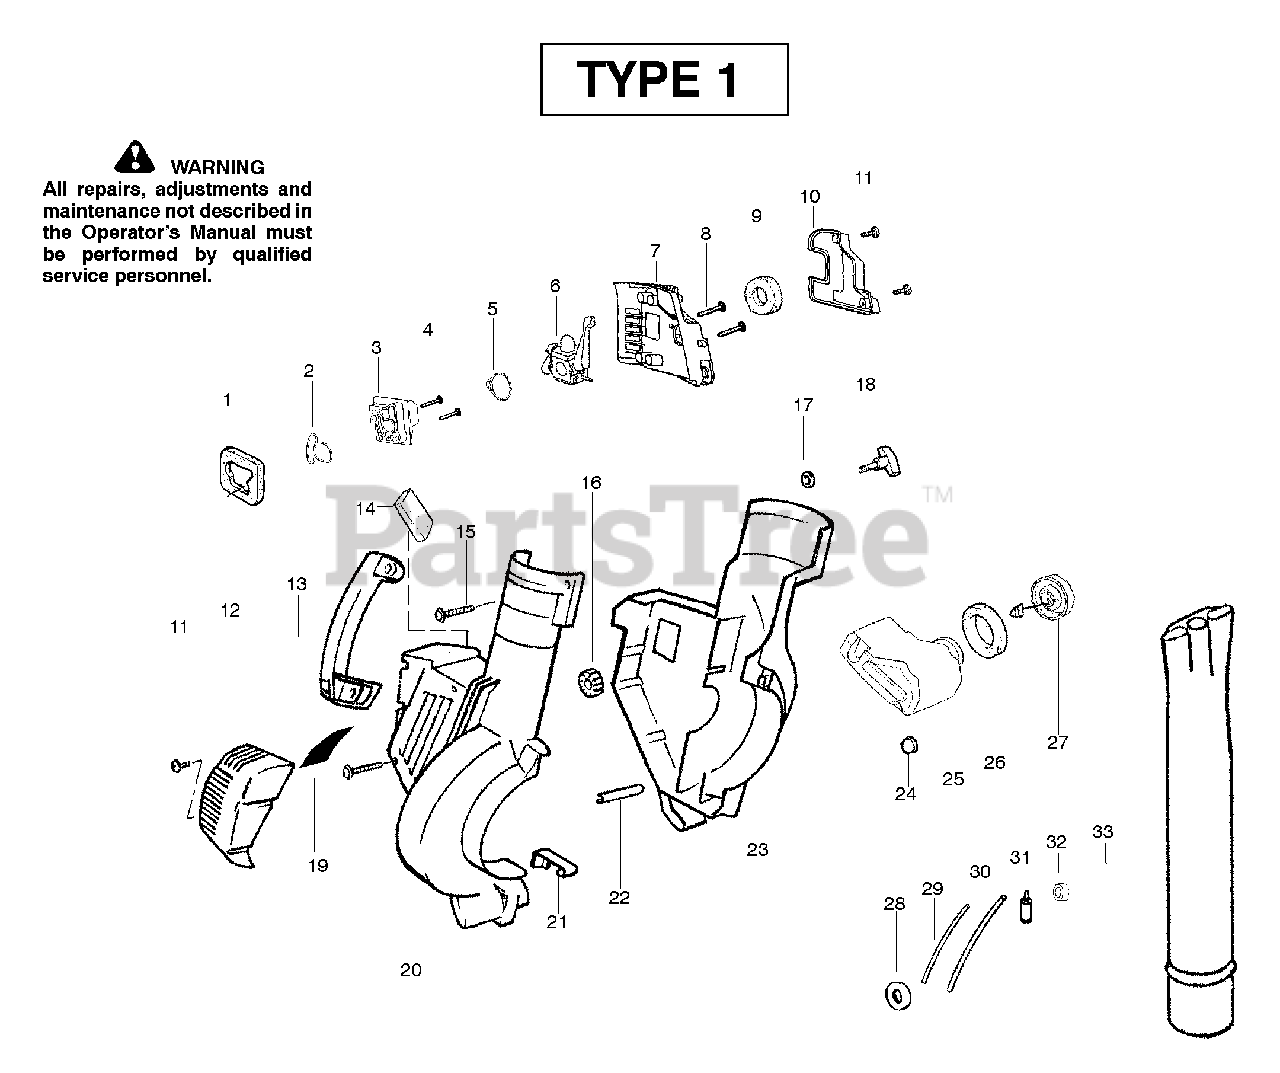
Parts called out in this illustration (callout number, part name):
1	Air Dam (kit)
2	Gasket-Adaptor (kit)
3	Carburetor Adaptor
5	Gasket-Carburetor (kit)
6	Kit-Carb Ass'y Zama-(C1Q-W11C)
6	Kit-Carb Ass'y Walbro-(WT-606)
8	Screw-Carb.
9	Filter-Air
10	Cover-Air Filter
12	Guard-Muffler
14	Foam - 71.12mm (kit)
16	Isolator
18	Knob-Tube Clamp
19	Reflector-Heat (kit)
20	Housing-Right
21	Spring-Cover Latch
22	Guide-Starter Rope
23	Housing-Left
24	Isolator-Crankcase
25	Assy-Fuel Tank
26	Gasket-Fuel Tank
27	Fuel Cap w/Retainer
28	Grommet-Shroud
29	Kit-Line Carb/Purge
30	Kit-Line Tank/Purge
31	Assy-Fuel Pick-up
32	Grommet-Fuel line (kit)
33	Tube-Blower
